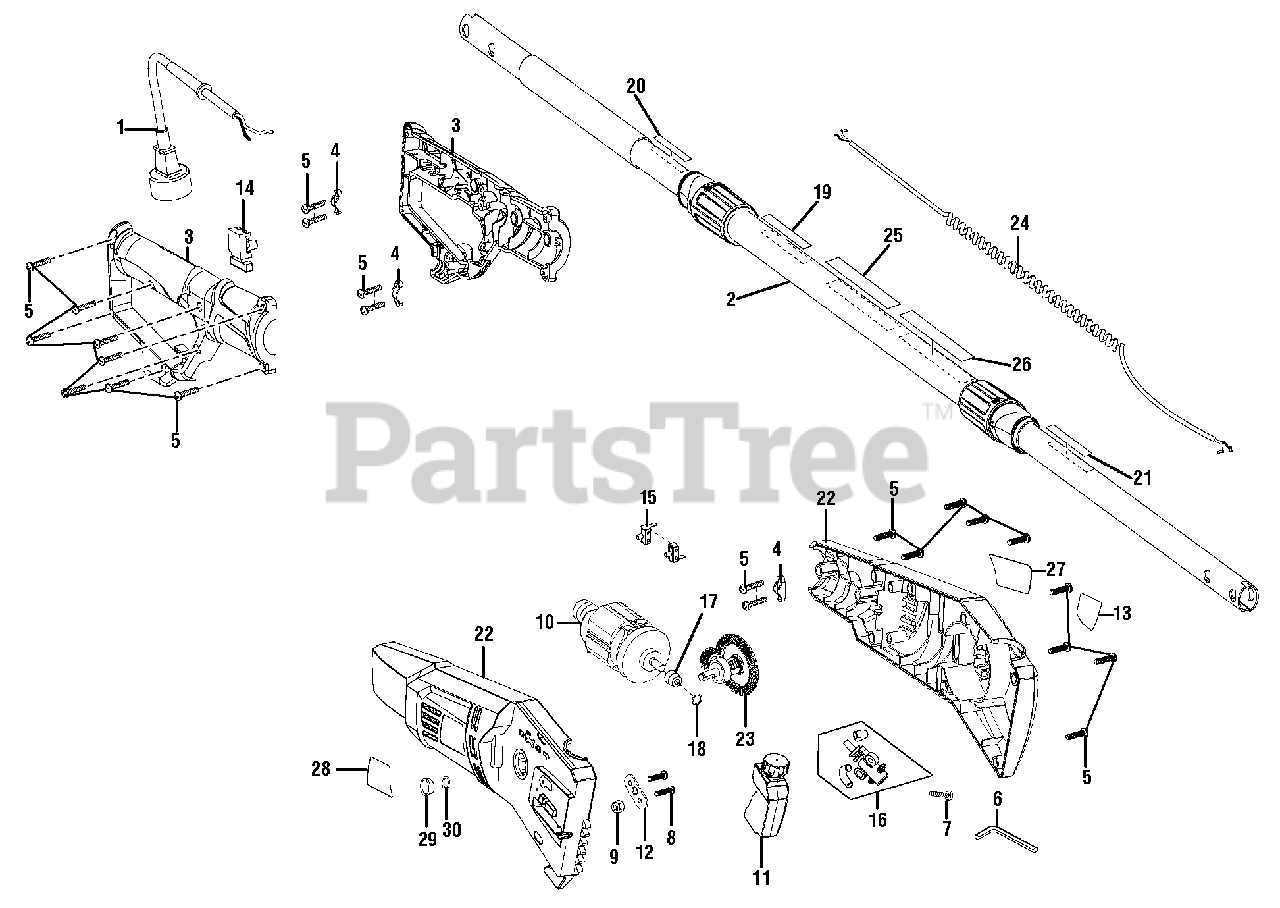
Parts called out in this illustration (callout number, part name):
1	Power Cord
2	Pole Assembly
3	Handle Assembly
4	Cord Clamp
5	Screw (M4 x 12 mm)
6	Hex Key (M5)
7	Screw (M4.2 x12 mm)
8	Screw (M3 x 10 mm)
9	Hex Nut (M6)
10	Motor Assembly
11	Oil Tank Assembly
12	Pressure Plate
13	Data Label (English)
14	Main Switch
15	Brush Assembly
16	Oil Pump Assembly
18	Retaining Ring
19	Warning Icon Label
20	Stop Label (Lower)
21	Stop Label (upper)
22	Housing Assembly
23	Output Shaft Assembly
24	Spring Cord Assembly
25	Warning Label
26	Warning Label (Spanish)
27	Logo Label (Left)
28	Logo Label (Right)
30	Felt Ring
